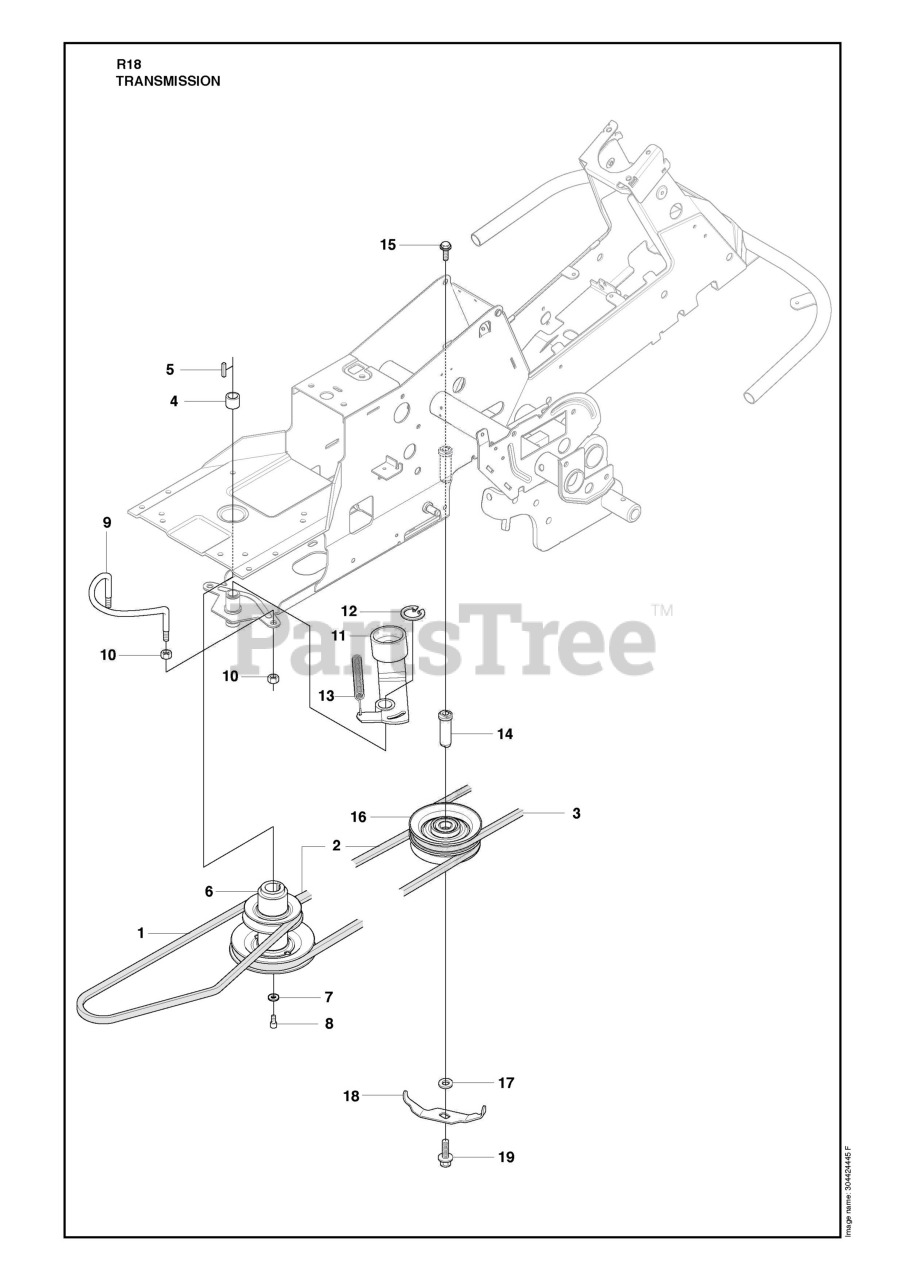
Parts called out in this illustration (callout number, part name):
1	BELT
2	BELT
3	BELT
9	Belt Guide
10	NUT
12	RETAINING RING SGA 25
14	SHAFT
18	BELT GUIDE
19	BOLT
